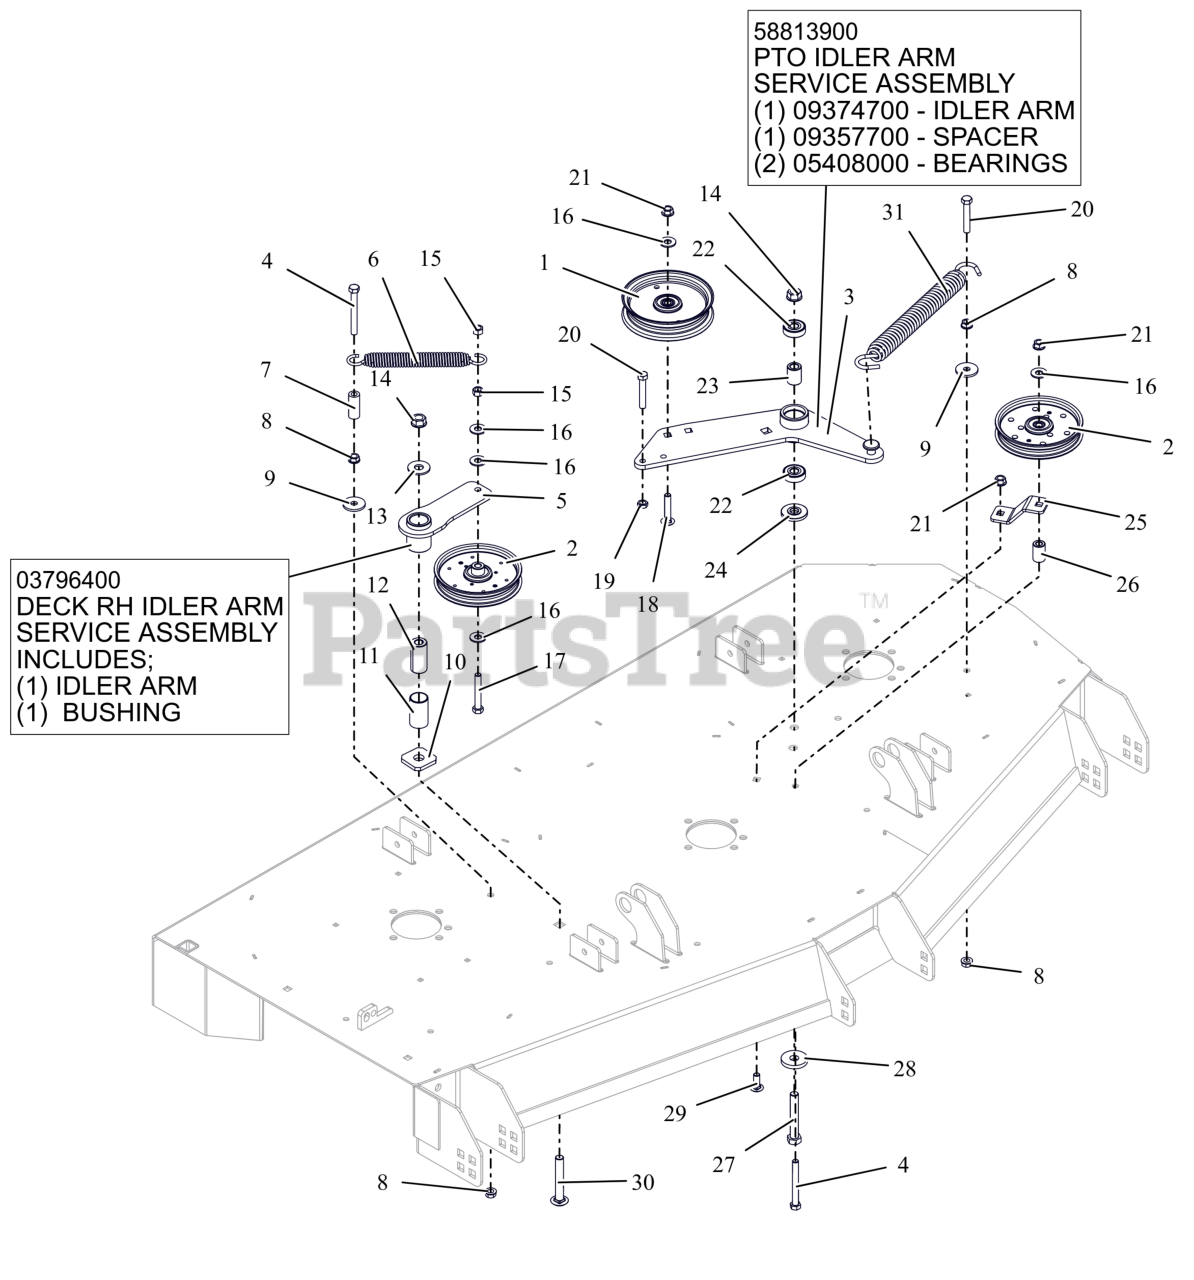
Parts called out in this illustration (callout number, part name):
1	IDLER- FLAT - 5.00" X .75"
2	IDLER- 5" FLANGED
3	WLDMT, IDLER ARM PT660
3	PTO IDLER ARM
3	SPACER .510 X .867 X 1.1485
3	BRG-BALL .500X1.38X.437
4	BLT, HEX .38-16X3.25 G5 ZCC
5	WMT, IDLER ARM - BLACK
5	ASM, IDLER ARM (DECK)
5	BSHG, 1.00X1.125X1.937
6	SPRING- EXTENSION
7	HOSE, .38 X 1.65
8	NUT, SPNLK-FLG .38-16 G5 ZCC
9	WSHR,FLT .406X1.375X.135 ZCC
10	WSHR-FLT .640X1.75X.250
11	BSHG, 1.00X1.125X1.937
12	BSHG, SPCR .502X.997X2.03 PM
13	WSHR,FLT .563X1.375X.109 ZCC
14	NUT-LK-CTR-FLG .500-13 GG ZCC
15	NUT-LK-CTR .38-16 ZC120
16	WSHR,FLT .438X1.00X.083 ZCC
17	BLT, HEX .38-16X2.50 G5 ZCC
18	BLT,RHSSN.375-16X2.00 G5 ZCC
19	NUT-JAM .375-16 G2 ZCC
20	BLT,HEX .38-16X2.25 G5 ZCC
21	NUT-LK-CTR-FLG .375-16 GF ZCC
22	BRG-BALL .500X1.38X.437
23	SPACER .510 X .867 X 1.1485
24	SPACER, IDLER ARM
25	PTO FIXED IDLER MTG BRKT -RED
26	BUSHING, SLV .380X.750X1.190
27	BLT,HEX .50-13X3.25 G5 ZCC
28	WSHR-FL-STL 0.557X1.625X0.25 ZCC
29	BLT,RHSSN .38-16X1.00 G5 ZCC
30	BTL,RHSSN .500-13 X 3.25 G5 ZCC
31	SPRING, EXTENSION
